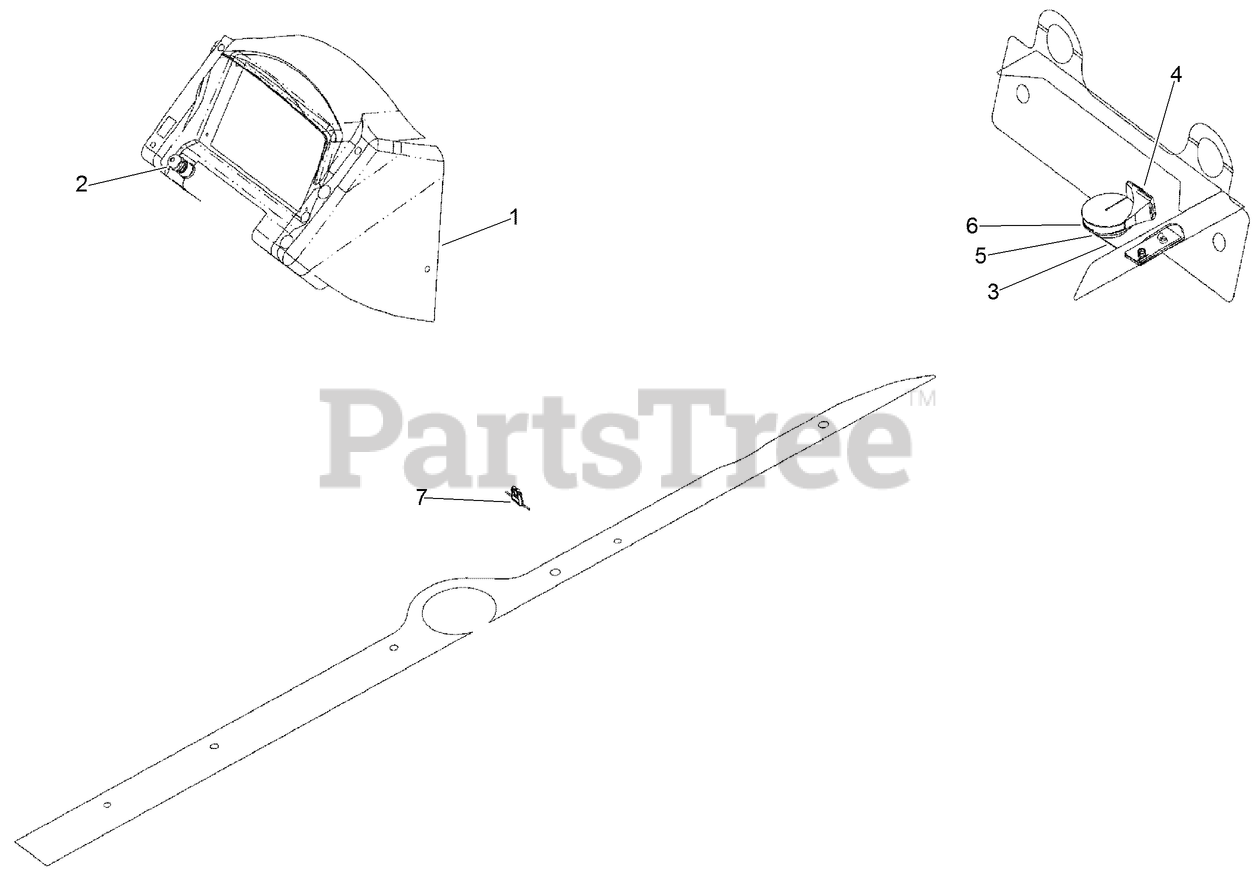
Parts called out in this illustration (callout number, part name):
1	DECAL - Horn
2	SWITCH-PUSH BUTTON (SEALED)
3	PLATE - Horn Bracket
4	ASSEMBLY - Horn
5	NUT - M5 Class 5 ZND
6	WASHER-FLAT
7	HARNESS-WIRE, HORN
